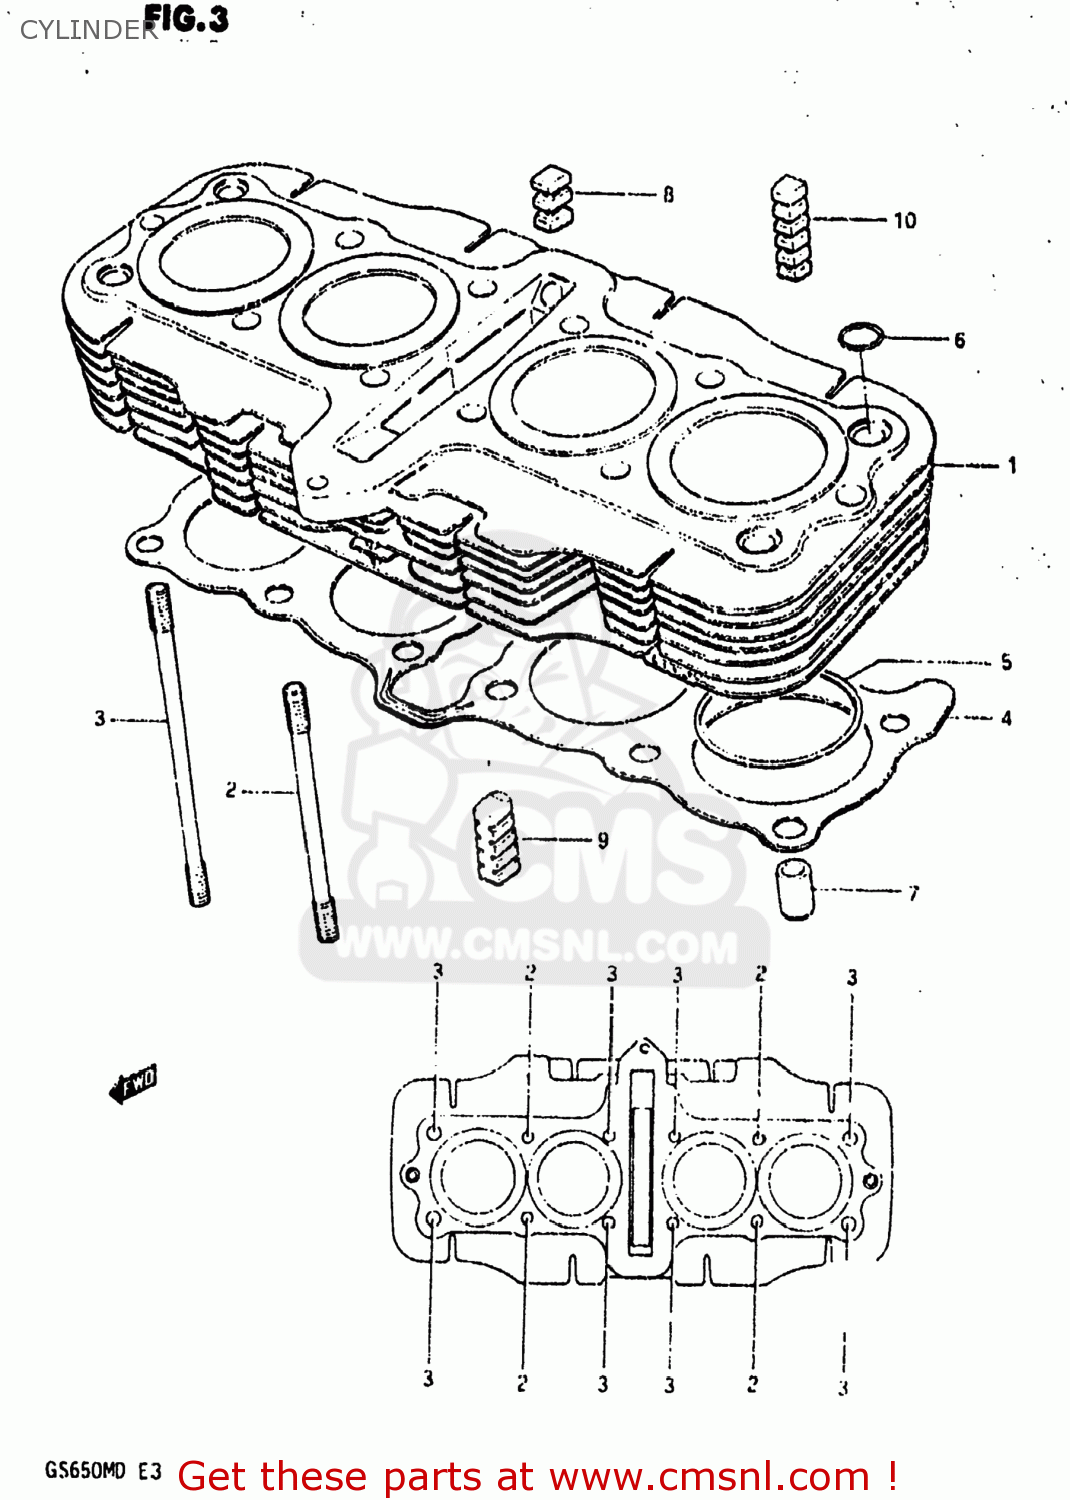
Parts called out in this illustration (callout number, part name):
1	CYLINDER
2	BOLT,STUD
3	BOLT,STUD
4	GASKET,CYLINDER (MCA)
5	O RING(D:2,ID:61)
6	O RING(D:1.9,ID:11.8)
7	PIN
8	PAD,CYLINDER
9	PAD,CYLINDER
10	PIN,EXHAUST VALVE
